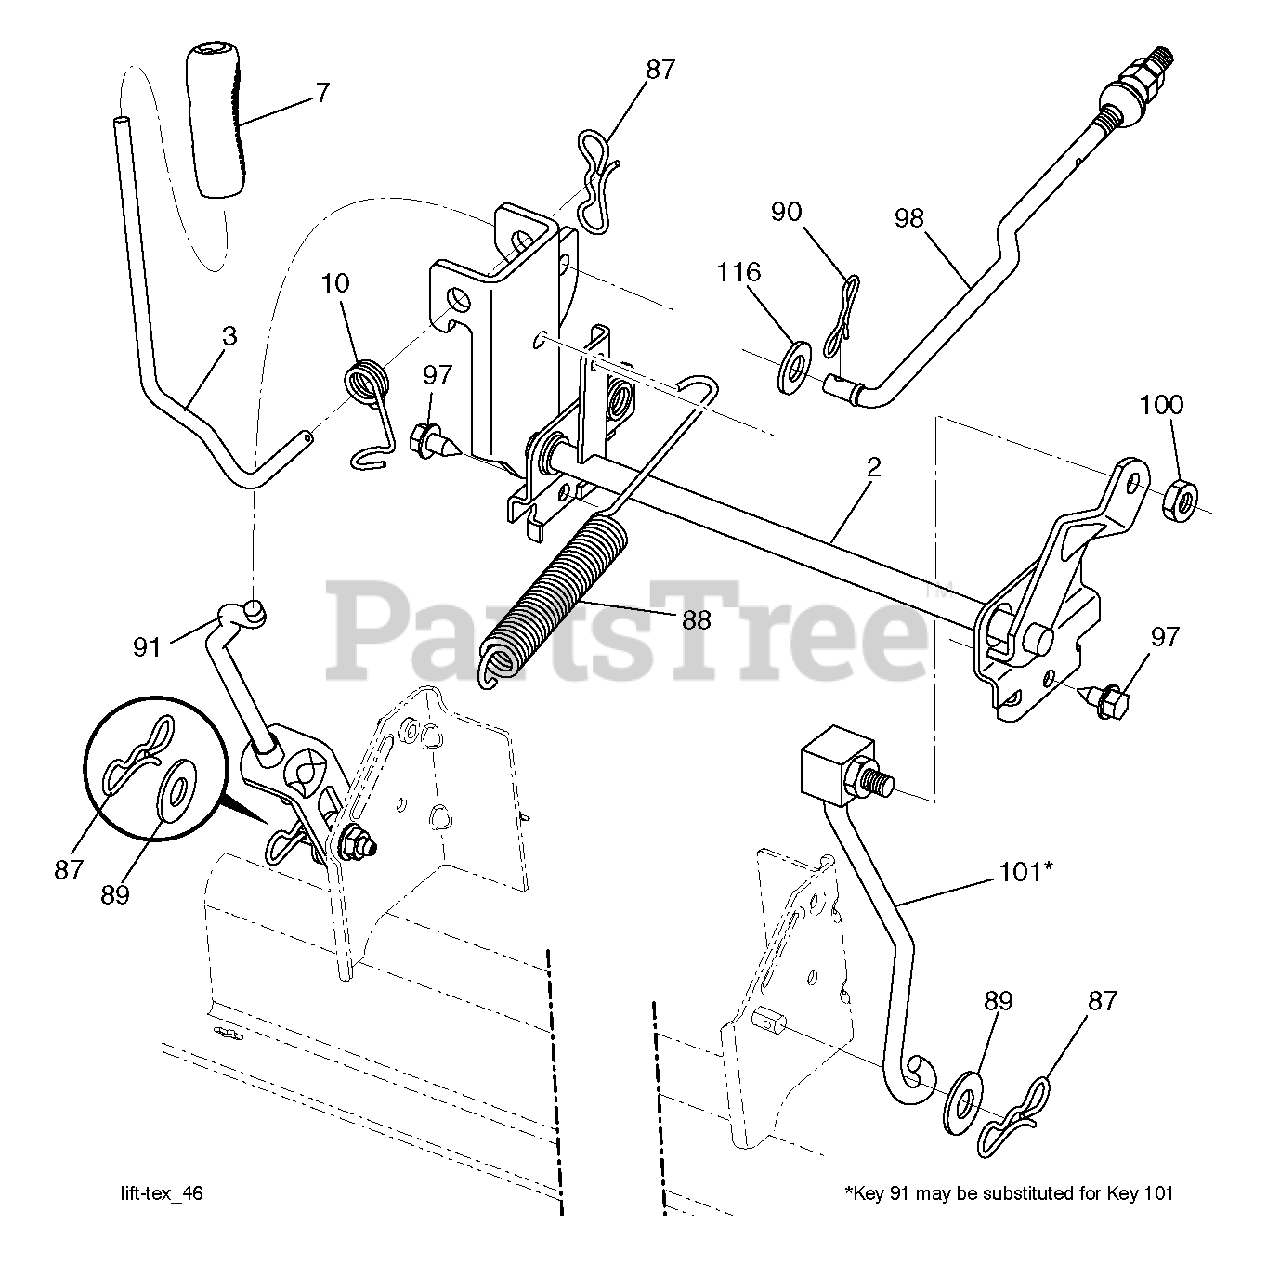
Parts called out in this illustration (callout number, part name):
2	SHAFT.ASM.CROSS.LIFT
3	LEVER.LIFT.HANDLE.LT
7	GRIP.HANDLE.LIFT.PVC.BLACK
10	SPRING.TORSION.LIFT.HANDLE
87	PIN.COTTER.7/16.BOW TI.
88	SPRING.LIFT.ASSIST
89	WASHER.CLEAR.ZINC
90	PIN.COTTER.5/16.BOW TI
91	LINK.ASM.LIFT.REAR
97	SCREW, 3/8-16X3/4
98	LINK.ASM.SUSP.FRONT.MW
100	LOCKNUT
101	LINK.ASM.LIFT.FIXE.38/42/46"
116	WASHER
